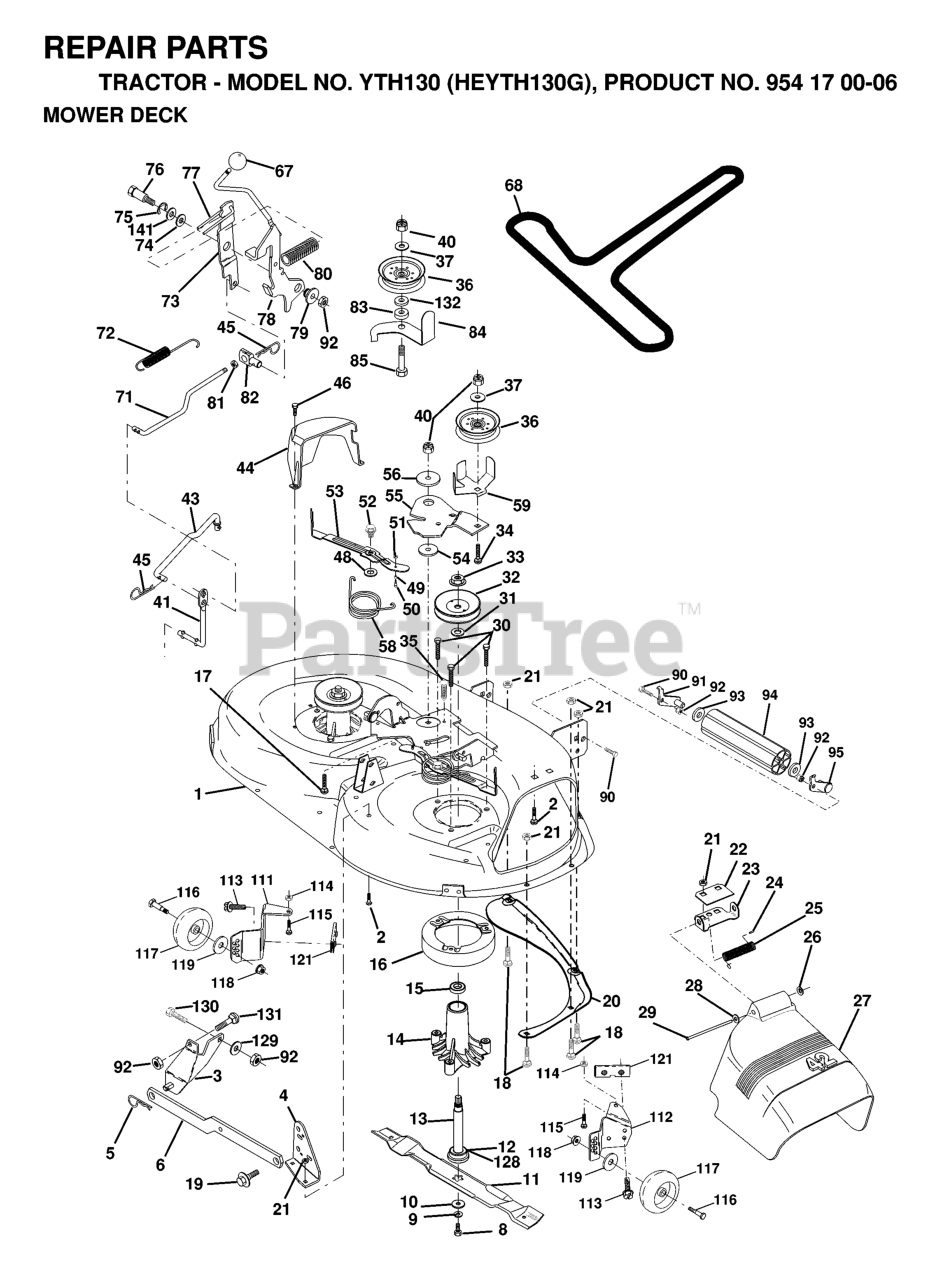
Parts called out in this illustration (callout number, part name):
1	DECK 42"
2	RP BOLT 5/16-18 X3/4 ZN/YEL GR
3	BRKT ASM SWAY BAR
4	BRKT DECK SW BAR
5	RETAINER-SPRNG RB
6	REAR SUSP ARM
8	BLADE BOLT
9	LOCKWASHER
10	WASHER.BLADE
11	BLADE 42", YTH 160
12	BEARING.BALL.#6204.(MANDREL)
13	SHAFT ASM VENT
14	HOUSING.MANDREL.VENTED (MACHD)
16	STRIPPER
17	BOLT
18	BOLT
19	BOLT SHD 5/16-18
20	BAFFLE.VORTEX
21	LOCKNUT
22	STIFFENER BRACKET
23	DEFLECTOR BRACKET
24	CAP-SLEEVE LT
25	SPRING TORSION
26	NUT PUSH M
27	SHIELD.DEFLECTOR.MOWER.42".BLK
28	Washer 11/32 x 5/8 x 16 Ga SD
29	ROD.HINGE
30	SCREW THDROL ROLLING WASHER HD
31	WASHER
32	PULLEY/MANDREL
33	NUT
35	FASTENER.XMAS.TREE
36	FLAT IDLER PULLEY
37	WASHER
43	CLUTCH ROD
44	GUARD MANDREL LH BLACK
45	RETAINER M
46	SCREW.1/4-20X5/8
49	ROLLER ASSY
52	BOLT.SHOULDER.5/16-18
53	ARM ASM PAD BRAD
54	HARDENED WASHER
55	ARM IDLER 42" MOWER LT/YT
56	SPACER RETAINER
59	GUARD, BELT
67	KNOB.CONTROL.7/16
71	CLUTCH ROD
72	RETURN SPRING
73	ARM CLUTCH SECONDARY
77	KEEPER SPRING
78	CLUTCH LEVER ASSY
79	BUSHING.FLANGE.E-RING.GROOVE
80	SPRING-CLUTCH (2 2 PW01)
81	NUT
82	TRUNNION.ADJUSTABLE.3/8-16
84	KEEPER.BELT.IDLER
85	BOLT
90	BOLT
91	BRACKET LH (A)
92	NUT
93	Washer 1 17/32 X 7/8 X 16 Ga
94	NOSE ROLLER
95	BRACKET RH (B)
111	BRACKET WHEEL GAUGE LH 42" DK
112	BRACKET WHEEL GAUGE RH 42" DK
113	SCREW.THDROL.5/16-18X3/4.TTY
114	NUT
115	BOLT.CARR.5/16-18X1/2
116	BOLT, SHOULDER
117	WHEEL GAGE DONUT
118	LOCKNUT
119	WASHER.5/16.FLAT.STE.STD.
121	BRACKET.EXTRUDED.GAGE.WHEEL
128	WASHER FELT
129	WASHER
131	BOLT D
132	Washer 13/32 x 1-3/8 x 13 Ga.
